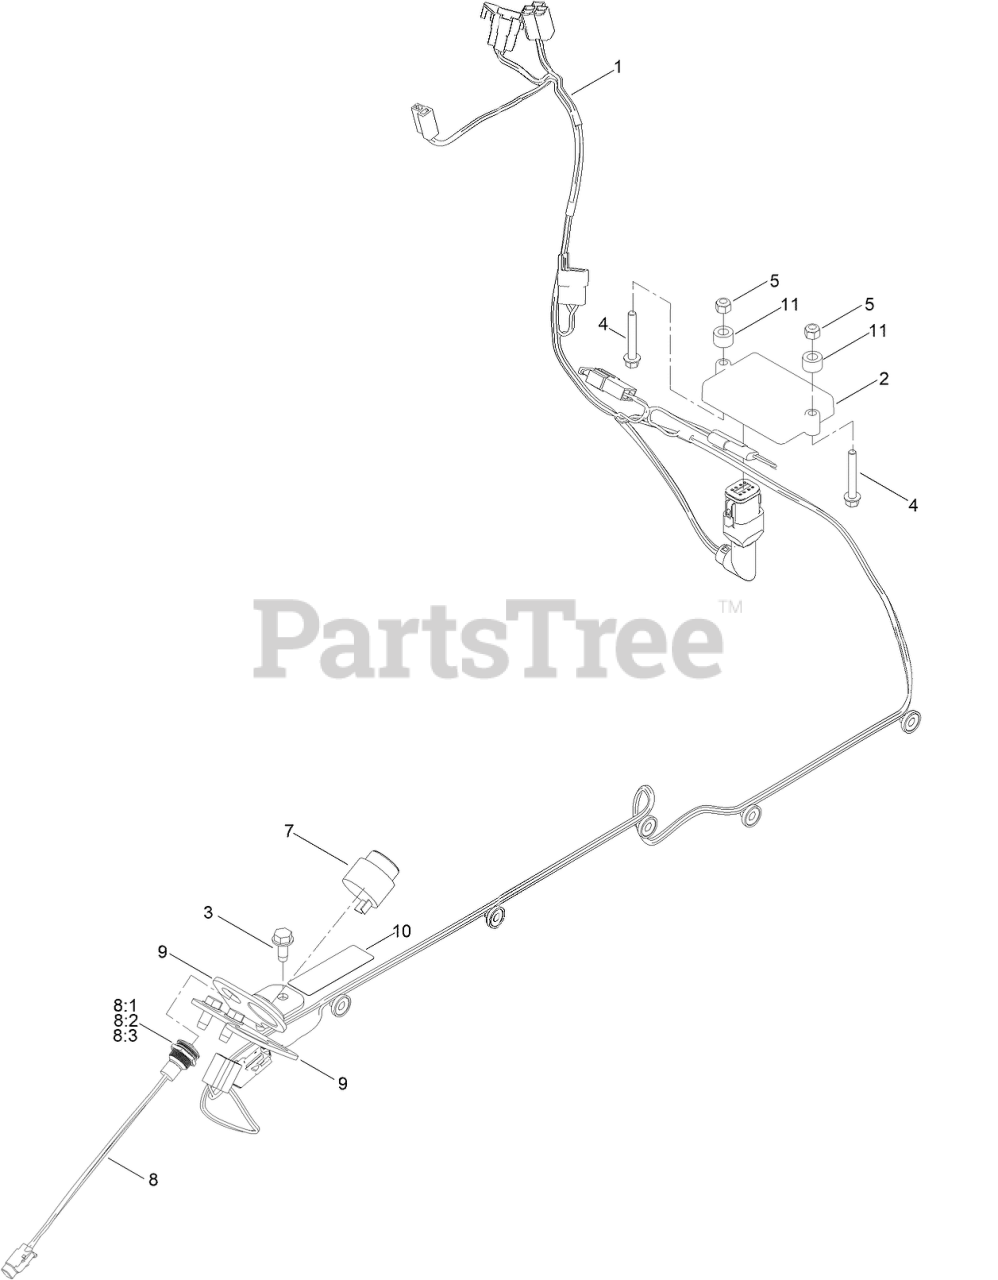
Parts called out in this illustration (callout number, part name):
1	HARNESS-WIRE, SLOPE SENSOR
2	CONTROLLER (FASM-TSM-0802)
3	SCREW-HWHTF
4	SCREW-HHF
5	NUT-HEX
7	AUDIO ALARM ASM
8	RED LED INDICATOR LAMP ASM
8:1	GASKET-LED
8:2	WASHER-LOCKING
8:3	NUT-FIXING
9	BRACKET-LIGHT
9	BRACKET-LIGHT (MYRIDE)
10	DECAL-SLOPE SENSOR
11	SPACER
